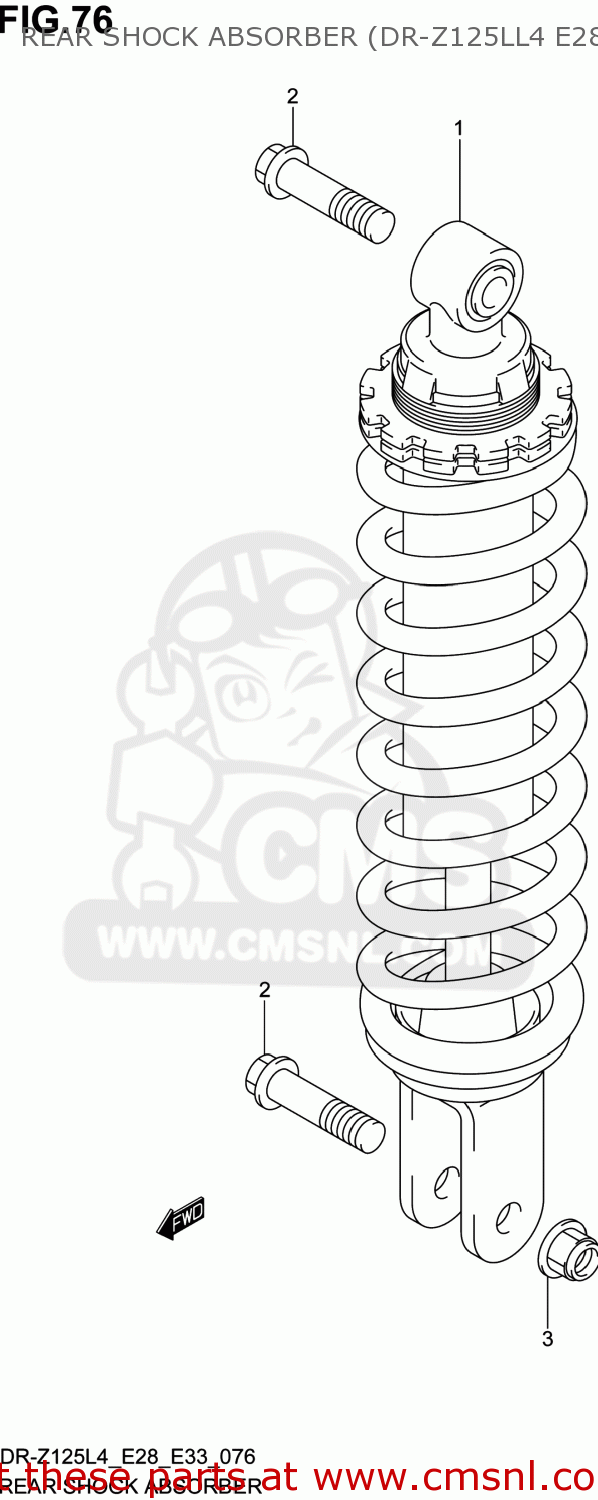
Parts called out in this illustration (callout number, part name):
1	ABSORBER ASSY,RR SHOCK
2	BOLT,RR CUSHION ROD LWR
3	NUT
